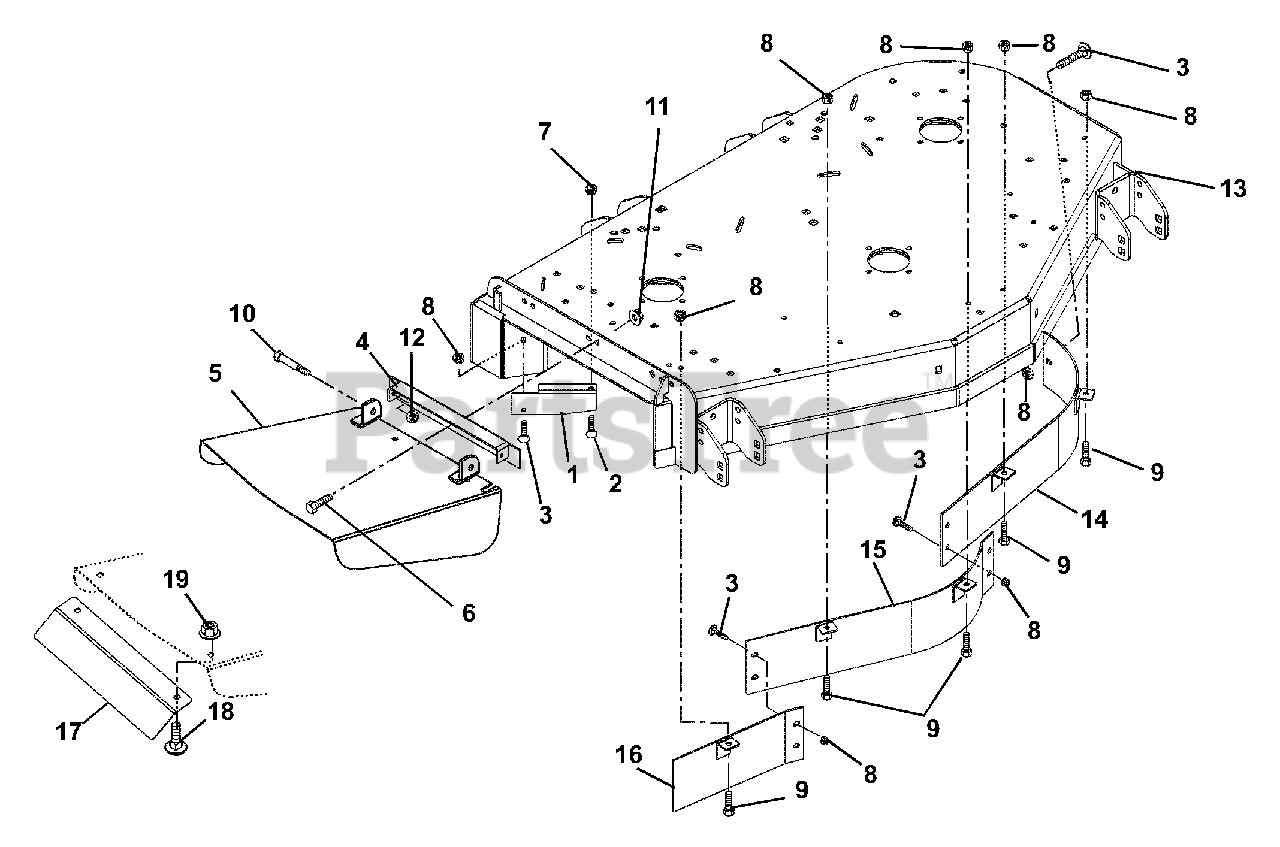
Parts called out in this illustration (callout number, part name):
1	DEFLECTOR, 60" (BLACK)
2	@BLT-RDHDSQNK .38-16X.75 G5YZ
3	@BLT-RDHDSQNK .31-18X.75 G5YZ
4	WMT, CHUTE BRKT
5	WMT, DISCHARGE CHUTE 60"
6	@BLT-HEX .38-16X1.00 GR5 YWZC
7	@NUT-LK-TOP-FLG .38-16 YWZC
8	@NUT-LK-TOP-FLG .31-18 YWZC
9	@BLT-HEX .31-18X.75 GR5 YWZC
10	BLT-SHLDR .38-16X.38 SKH
11	@NUT-SPNLK-FLG .375-16 YWZC
12	@NUT-LK-CTR .38-16 YWZC
13	60" 7 GA MOWER DECK - RED
14	BAFFLE - LEFT FRONT - 60"
15	BAFFLE - CENTER FRONT - 60"
16	BAFFLE - RIGHT FRONT - 60"
17	DEFLECTOR, CHUTE
18	@BLT-RDHDSQNK .38-16X.75 G5YZ
19	@NUT-LK-TOP-FLG .38-16 YWZC
